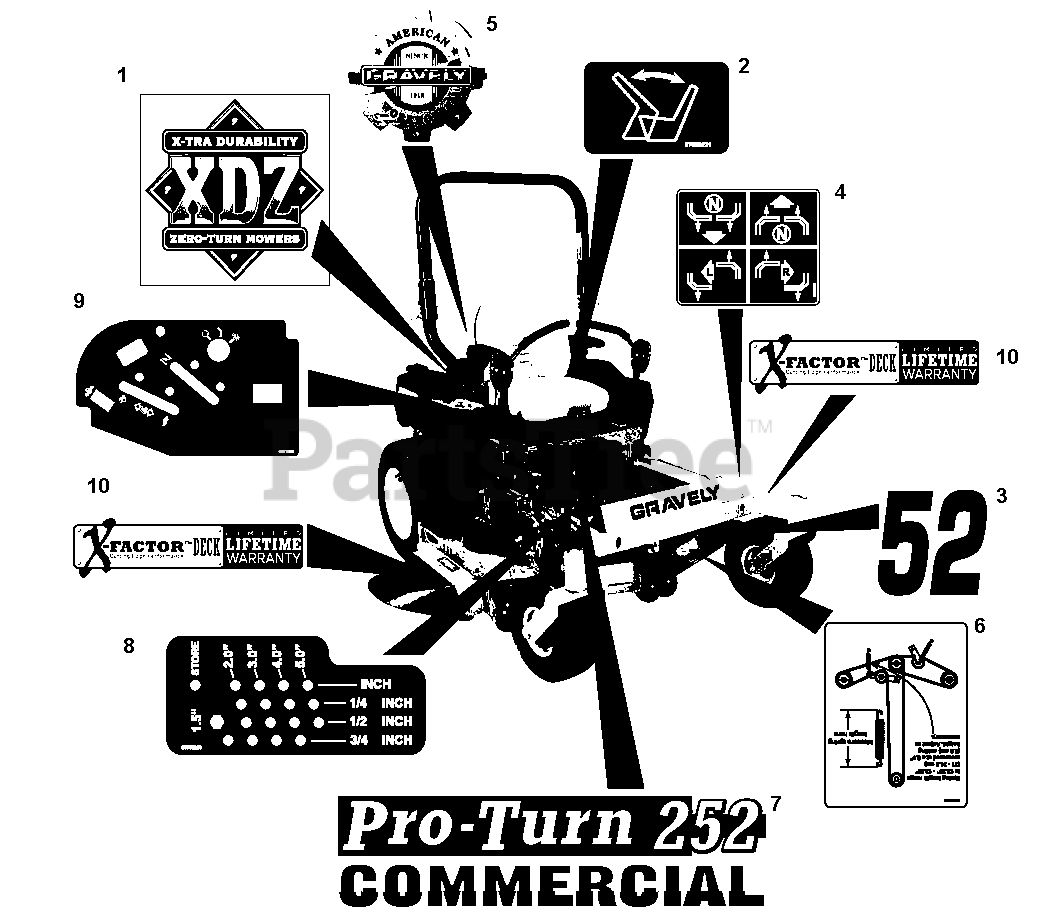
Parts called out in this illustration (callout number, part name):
1	Decal, XDZ
2	Decal, Seat Release
3	Decal, 52 (992200, 205, 197)
4	Decal, Instructional- Steering
5	Decal, Gravely Heritage, Large
6	Decal, Belt Routing
7	Decal, Pro-Turn 252 (992200, 205, 197)
8	Decal, Height of Cut
9	Decal, Control Panel (992200, 201, 203, 197, 198)
10	Decal, X-Factor Deck
